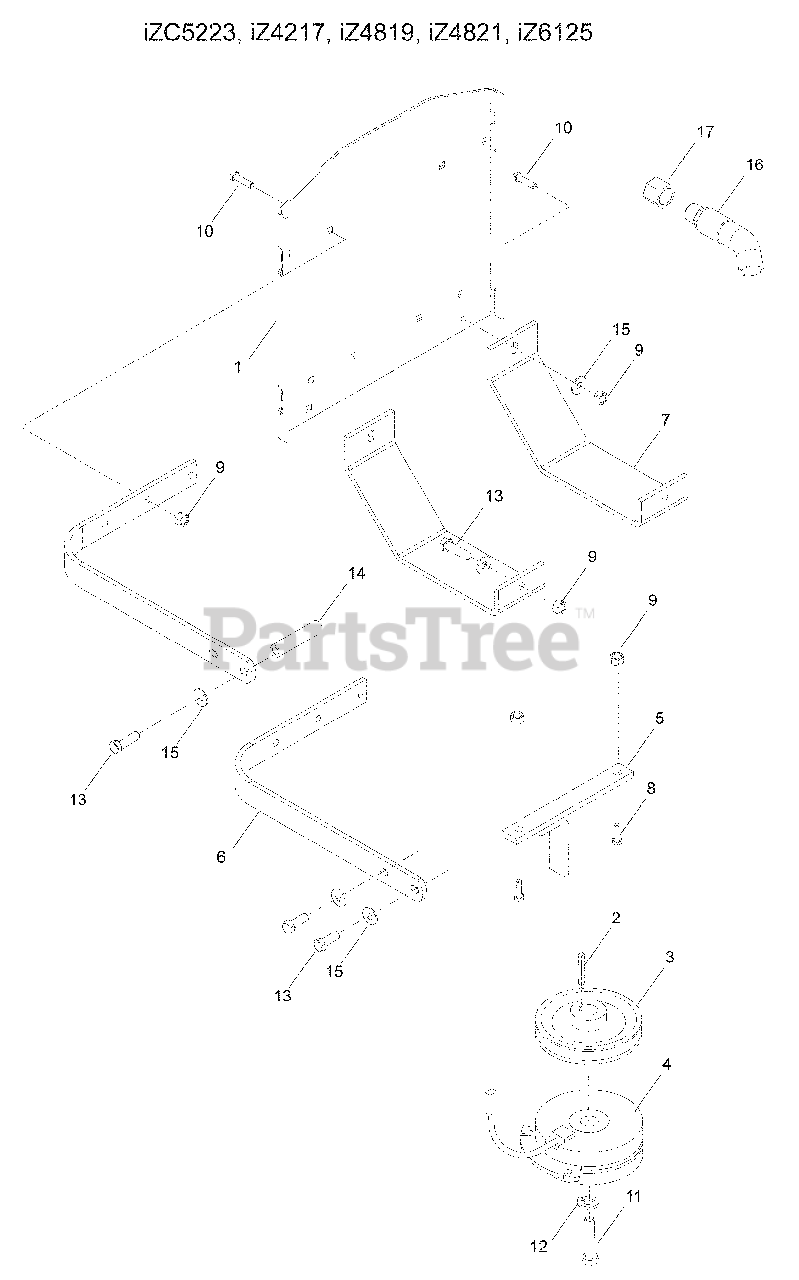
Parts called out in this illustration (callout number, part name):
1	GUARD, REAR
2	KEY, ¼ SQ x 1¼
4	CLUTCH, iZ6125
5	TIE DOWN, CLUTCH
6	STRAP
7	SKID PLATE
8	HCS 5/16-18 x 1¾
9	NUT 5/16-18 HEX NYLOC
10	RHSNB 5/16-18 x 1
11	HCS 7/16-20 x 2½
12	WASHER 7/16 SLW
13	HCS 5/16-18 x 1 iZ6125, iZC5223
14	SPACER iZ4217, iZ4819, iZ4821, iZC5221
15	WASHER 5/16 STD FLT
16	HOSE, DRAIN iZC5221, iZC5223, iZ4821, iZ6125
17	PLUG, OIL iZC5221, iZC5223, iZ4821, iZ6125
